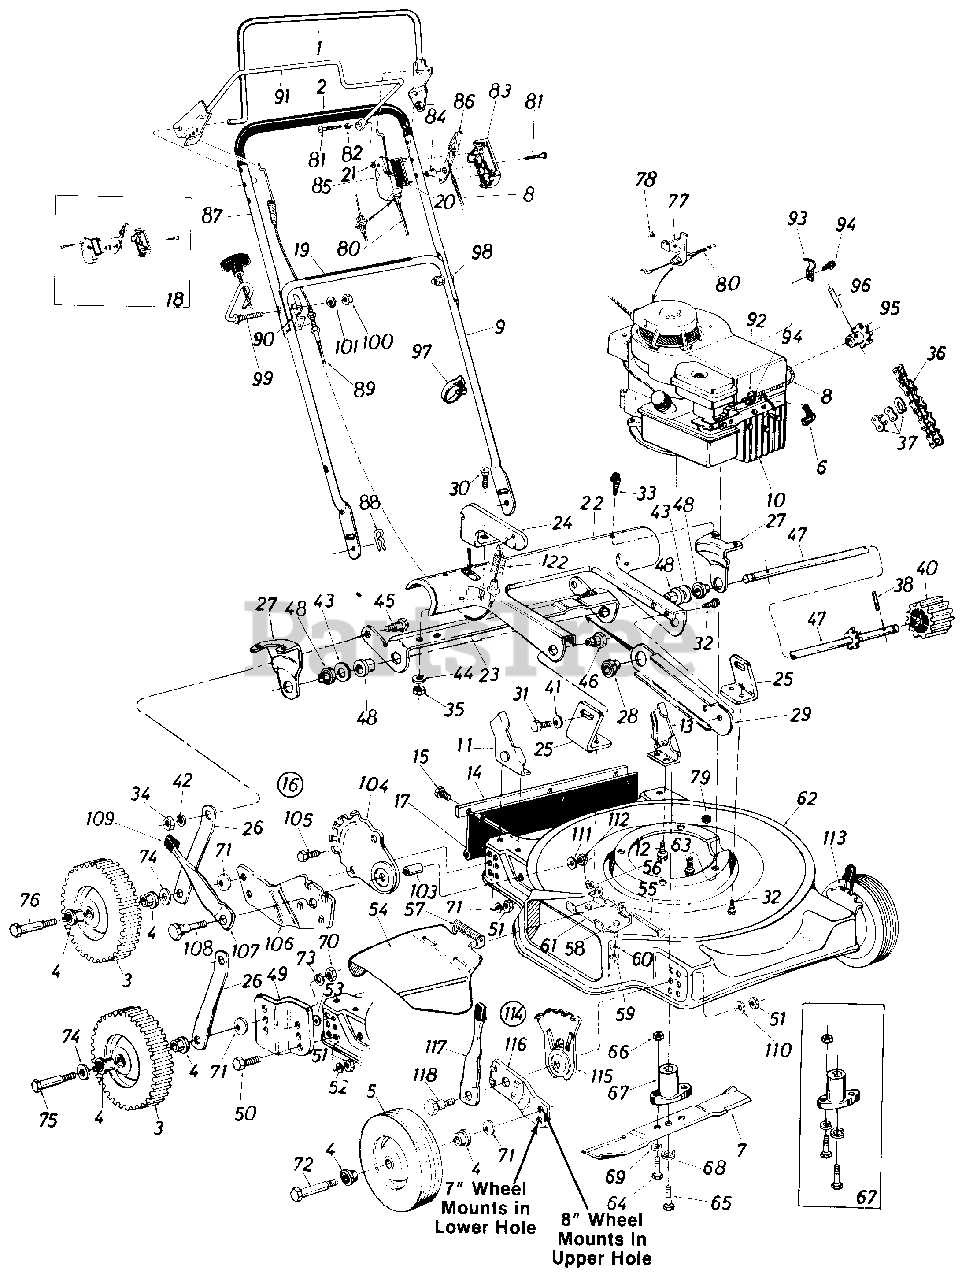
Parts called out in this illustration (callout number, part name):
1	Control Handle Ass'y.-L.H.
2	Grip
3	Rear Wheel Ass'y. Comp.- 8 x 1.75
4	Flange Brg.-1/2" I.D.
5	Front Wheel Ass'y. Comp.
6	Spark Plug Boot
7	Blade 22"
8	Throttle Wire-53.0"
9	Lower Handle (Chrome)
10	Engine
11	Handle Brkt. Ass'y.-R.H.
12	Hex Wash. Hd. "B"-Tap Scr. 5/16-18 x .50" Lg.
13	Handle Brkt. Ass'y.-L.H.
14	Retainer Strip
15	Hex AB-Tap Scr. 1/4 x .62" Lg.
16	R.H. Height Adj. Comp.
17	Rear Flap Ass'y.
18	Kit-Control Housing Comp.
19	Control Labels
21	Fl-Wash. .203 I.D. x .406 O.D.
22	Pinion Pivot Cover 22"
23	Cam
24	Engagement Arm
25	Pivot Brkt.
26	Link 4.58 x .88
27	Axle Brkt.
28	Flanged Ball Brg. .500" I.D.
29	Brg. Support
30	Carriage Bolt 1/4-20 x .50" Lg.
31	Hex Bolt 3/8-16 x .50" Lg.
32	Hex "B"-Tap Scr. 1/4" x .38" Lg.
33	Hex Wash. Hd. "AB"-Tap Scr. 1/4" x.62" Lg.
34	Hex Nut 5/16-18 Thd.
35	Hex Nut 1/4-20 Thd.
36	#48 Chain 1/2" Pitch 49 Links
37	#48 Master Link
38	Spring Pin Spir. 3116" Dia. x 1.25" Lg.
40	Drive Pinion
41	Bell-Wash. .400" I.D. x .88" O.D. x .060
42	L-Wash. 5/16" I.D.
43	Fl-Wash. .531" I.D. x .930" O.D. x .050
44	L-Wash. 1/4" I.D.
45	Shld. Bolt .437" Dia. x .162
46	Shld. Nut .625" Dia. x .162
47	Pinion Shaft wl7 Tooth Sprocket
48	Hex Flange Brg. x .506" I.D.
49	Wheel Brkt.
50	Hex Bolt 3/8-16 x .75" Lg.*
51	Hex Nut 3/8-16 Thd.*
52	Bell-Wash. .400" I.D. x .88" O.D.
53	Fl-Wash. .38" I.D. x .620" O.D.
54	Chute Deflector Ass'y.-Comp.
55	Pivot Pin
56	Cap Speed Nut 1/4" Rod
57	Torsion Spring
58	Hex Bolt 1/4-20 x .50" Lg.*
59	Hex Nut 1/4-20 Thd.*
60	L-Wash. 1/4" I.D.*
61	Hinge Plate
62	22" Deck Ass'y.
63	Hex Wash. Hd. TT-Tap Scr. 3/8-16 x 1.0" Lg.
64	Hex Bolt 5/16-24 x 1.00" Lg. (Grade 5)
65	Hex Bolt 3/8-24 x 2.25" Lg. (Grade 5)
66	Hex Nut 5/16-24 Thd.
67	Blade Adapter Kit
68	L-Wash. 3/8" I.D.-H.D.
69	L-Wash. 5/16" I.D.*
70	Hex Nut 3/8-16 Thd.*
71	Bell-Wash. .400" I.D. x .88" O.D.
72	Front Axle Bolt
73	L-Wash. 3/8" I.D.*
74	Fl-Wash. .531" I.D. x .93" O.D.
75	Rear Axle Bolt
76	Rear Axle Bolt
77	Cable Bracket
78	Pop Rivet .156" Dia. x .379
80	Control Cable-39.0"
81	Truss Mach. self-Tap Scr. #12 x 1.50" Lg.
82	Spacer.2;" I.D.
83	Control Panel Half
84	Control Disc Pin
85	Clutch Panel Half
86	Throttle Control Lever
87	Upper Handle (Chrome)
88	Hairpin Cotter
89	Clutch Cable w/Spring
90	Cable Mtg. Brkt.
91	Drive Control Handie
92	Casing Clamp
93	Casing Clamp
94	Hex "B"-Tap Scr. #10 x .38"
95	10 Tooth Sprocket Ass'y.
96	Spiral Pin 3/16" Dia. x 1.00'
97	Cable Tie
98	Curved Hd. Carriage Bolt 5/16-18 x 1.38" Lg.
99	Rope Guice Bolt
100	Hex Nut 5/16-18 Thd.
101	L-Wash. 5/16" I.D.
103	Spacer.395" I.D. x .5031' O.D. x .562" Lg.
104	Index Plate
105	Hex Bolt 3/8-16 x .75" Lg.
106	Pivot Bar R.H.
107	Spring Lever
108	Shoulder Bolt .500" Dia. x 3.75" Lg.
109	Spring Lever Knob
110	Bell-Wash. .39 I.D. x 1.13 O.D.
111	Bell-Wash. .336" I.D. x .86" O.D.
112	Hex L-Nut 5/16-18 Thd.
113	Height Adj. Ass'y.-Comp-L.H.
114	Height Adj. Ass'y.-Comp-R.H.
115	Height Adj. Plate
116	Pivot Bar
117	Spring Lever Ass'y. w/Knob
118	Shoulder Bolt .500" Dia. x .375" Lg.
122	Compression Spring .47" O.D. x 1.93" Lg.
